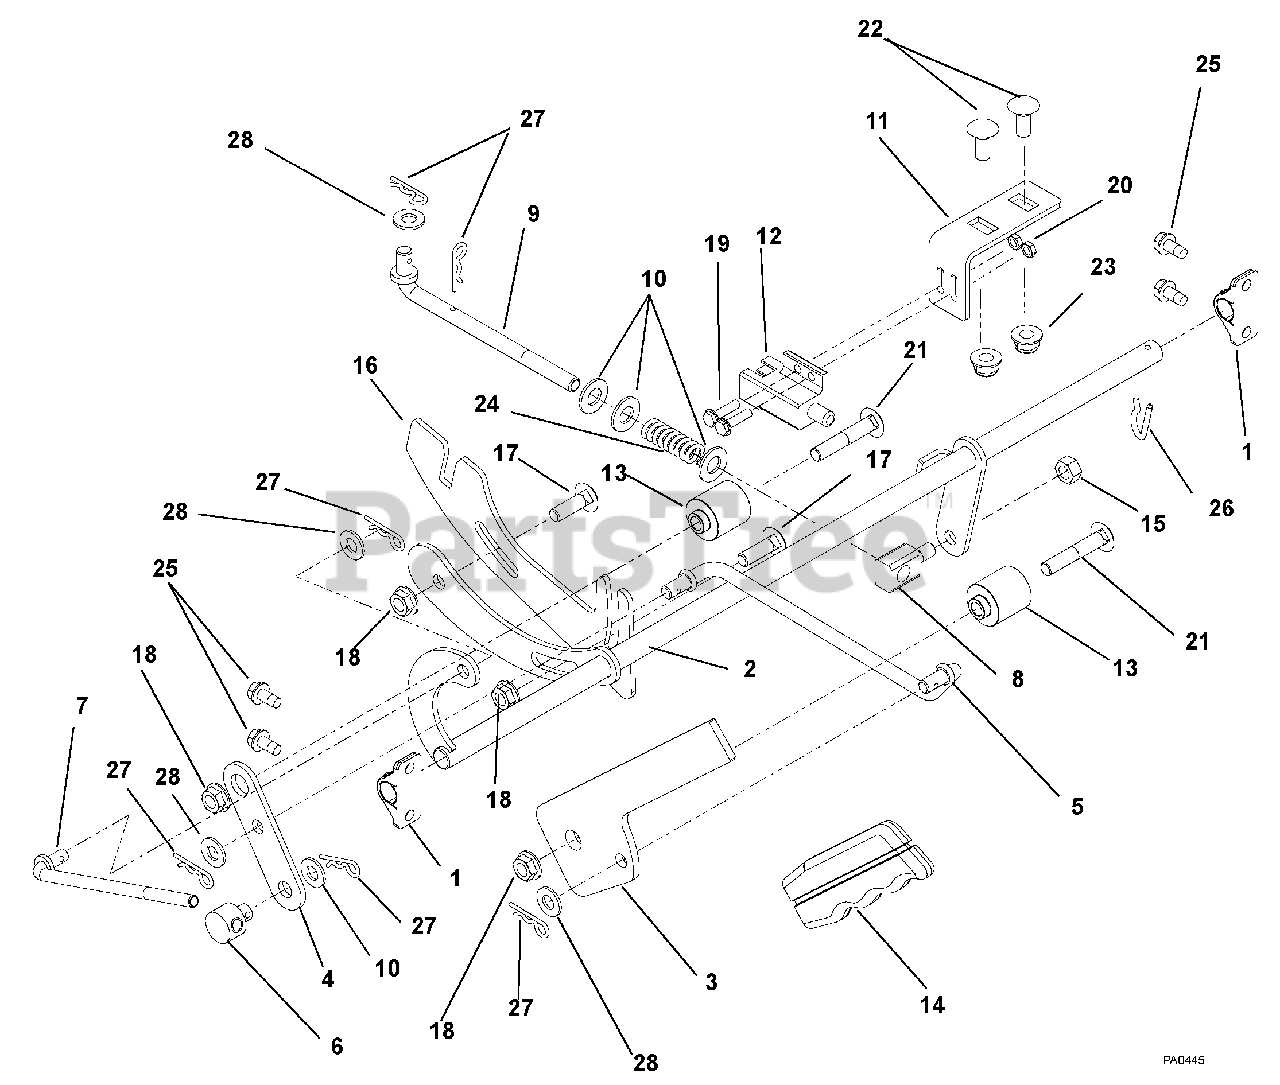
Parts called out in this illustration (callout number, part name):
1	BUSHING-.50 CLAMP BLOCK MOLDED
2	WMT, BRAKE CROSS SHAFT
3	HANDLE, PARKING BRAKE
4	BRACKET, MIDDLE PARKING BRAKE
5	ROD, PARKING BRAKE HANDLE
6	TRUNNION, BRAKE .31-18 UNC
7	BRAKE LINK
8	PIN, PIVOT/TRUNNION
9	BRAKE LINK- .375-24
10	@WSHR-FL-STL.406X.812X.065 YWZ
11	BRACKET, PARKING SWITCH MOUNT
12	SWITCH,INTERLOCK
13	SPCR, FLG .32X.49X.192X1.00
14	GRIP, PARKING BRAKE (YELLOW)
15	@NUT-LK-CTR .31-18 YWZC
16	INTERLOCK, FWD/REV
17	@BLT-RHDSSQNK .31-18X1.00 G5YZ
18	@NUT-LK-TOP-FLG .31-18 YWZC
19	@SCR-MCH 10-24X.75 HWH YWZC
20	@NUT-LK-NYL 10-24 W/INSRT YWZC
21	BLT-RDHDSQSHK .31-18X1.75 YWZC
22	@BLT-RDHDSQNK .31-18X.75 G5YZ
23	@NUT-LK-NYL-FLG .31-18 YWZC
24	SG-COMP .093X.59X1.50
25	SCR-TAP .25-20X.50 HWH TR YWZ
26	CLIP, SPRING
27	PIN-HAIR INT .08X.18X1.18 YWZC
28	@WSHR-FL-STL.344X.688X.065YWZC
